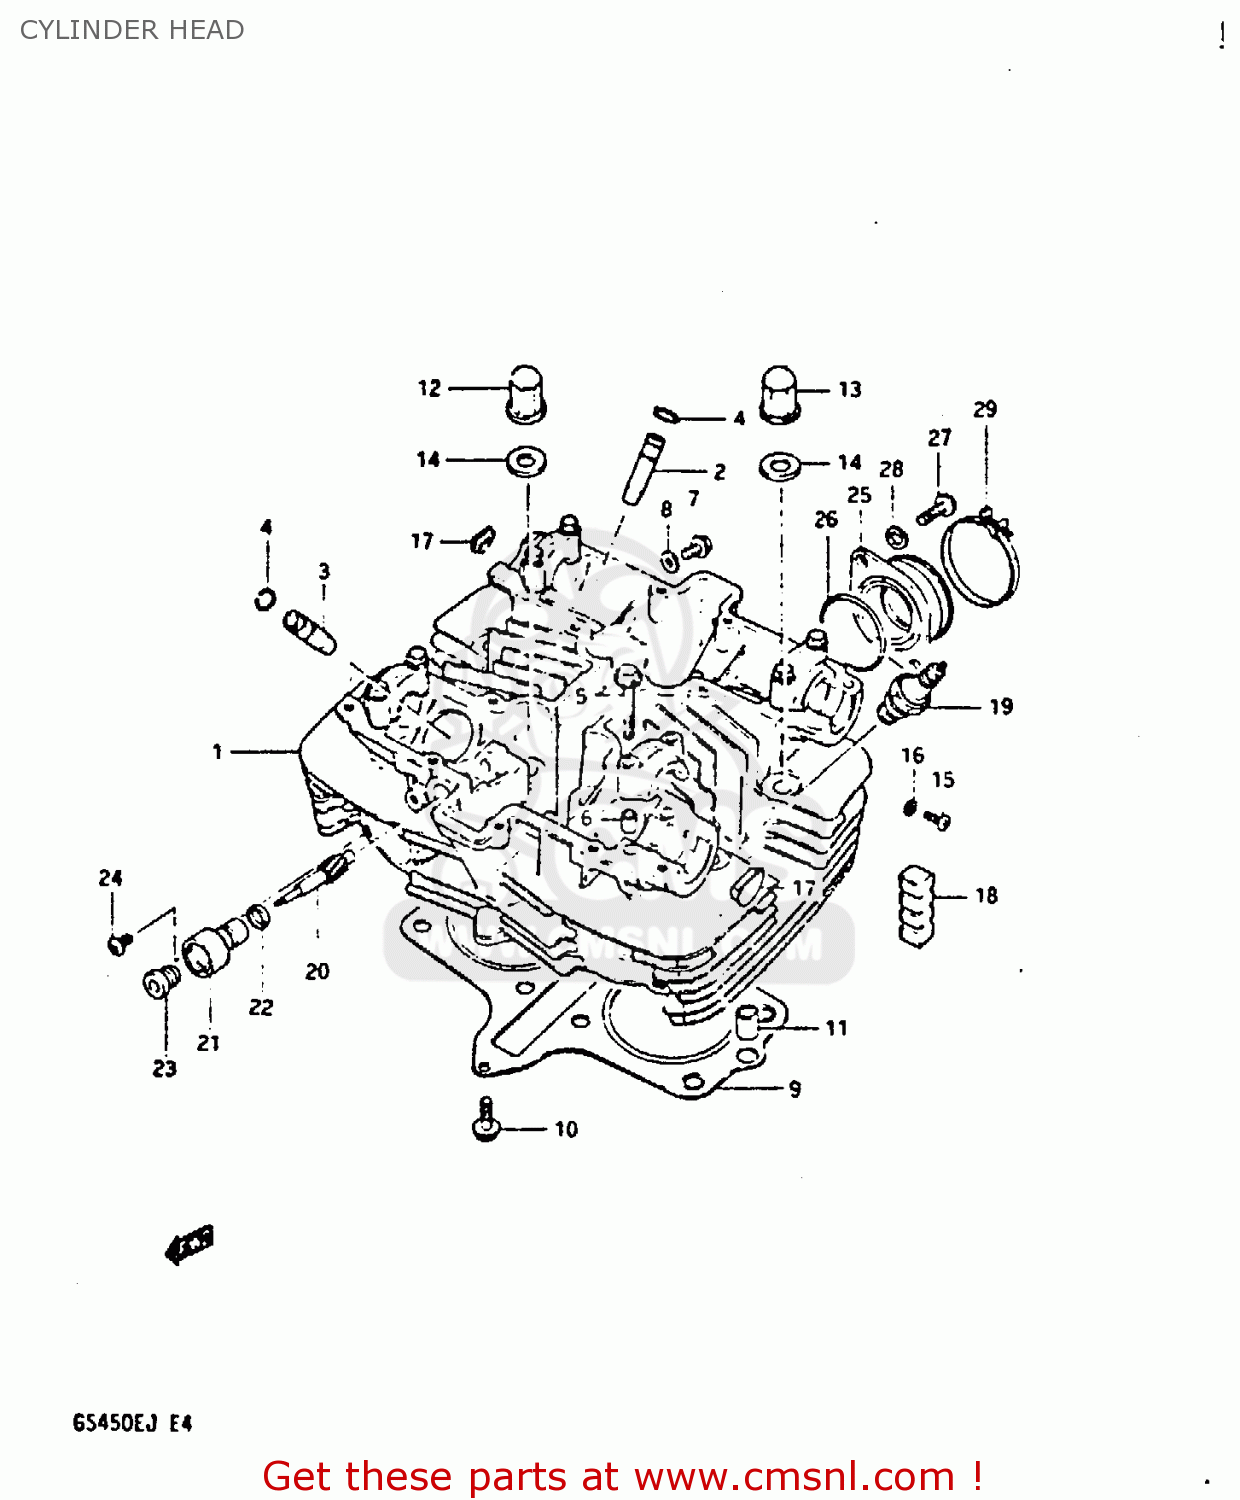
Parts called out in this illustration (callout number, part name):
1	HEAD SET,CYLINDER
2	GUIDE,INTAKE VALVE
3	GUIDE,EXHAUST VALVE
4	RING,SNAP
5	BOLT(6X39)
6	PIN(6.2X8X11)
7	BOLT
8	GASKET(5.8X13X1.2) (NAS)
9	GASKET,CYLINDER HEAD (MCA)
10	BOLT 6X30
11	PIN
12	NUT
13	NUT
14	GASKET(10.5X22X2) (NAS)
15	SCREW
16	GASKET(5.3X9.3X1.2) (NAS)
17	PLUG
18	PAD,CYLINDER
19	PLUG,SPARK
20	GEAR,TACHOMETER DRIVEN
21	SLEEVE,TACHOMETER DRIVE GEAR
22	SEAL,TACHOMETER DRIVEN
23	SEAL,OIL(5X12X8)
24	SCREW(5X12)
25	PIPE,INTAKE
26	O-RING (D:2.4 ID:39.7)
27	SCREW
28	WASHER,LOCK
29	CLAMP
